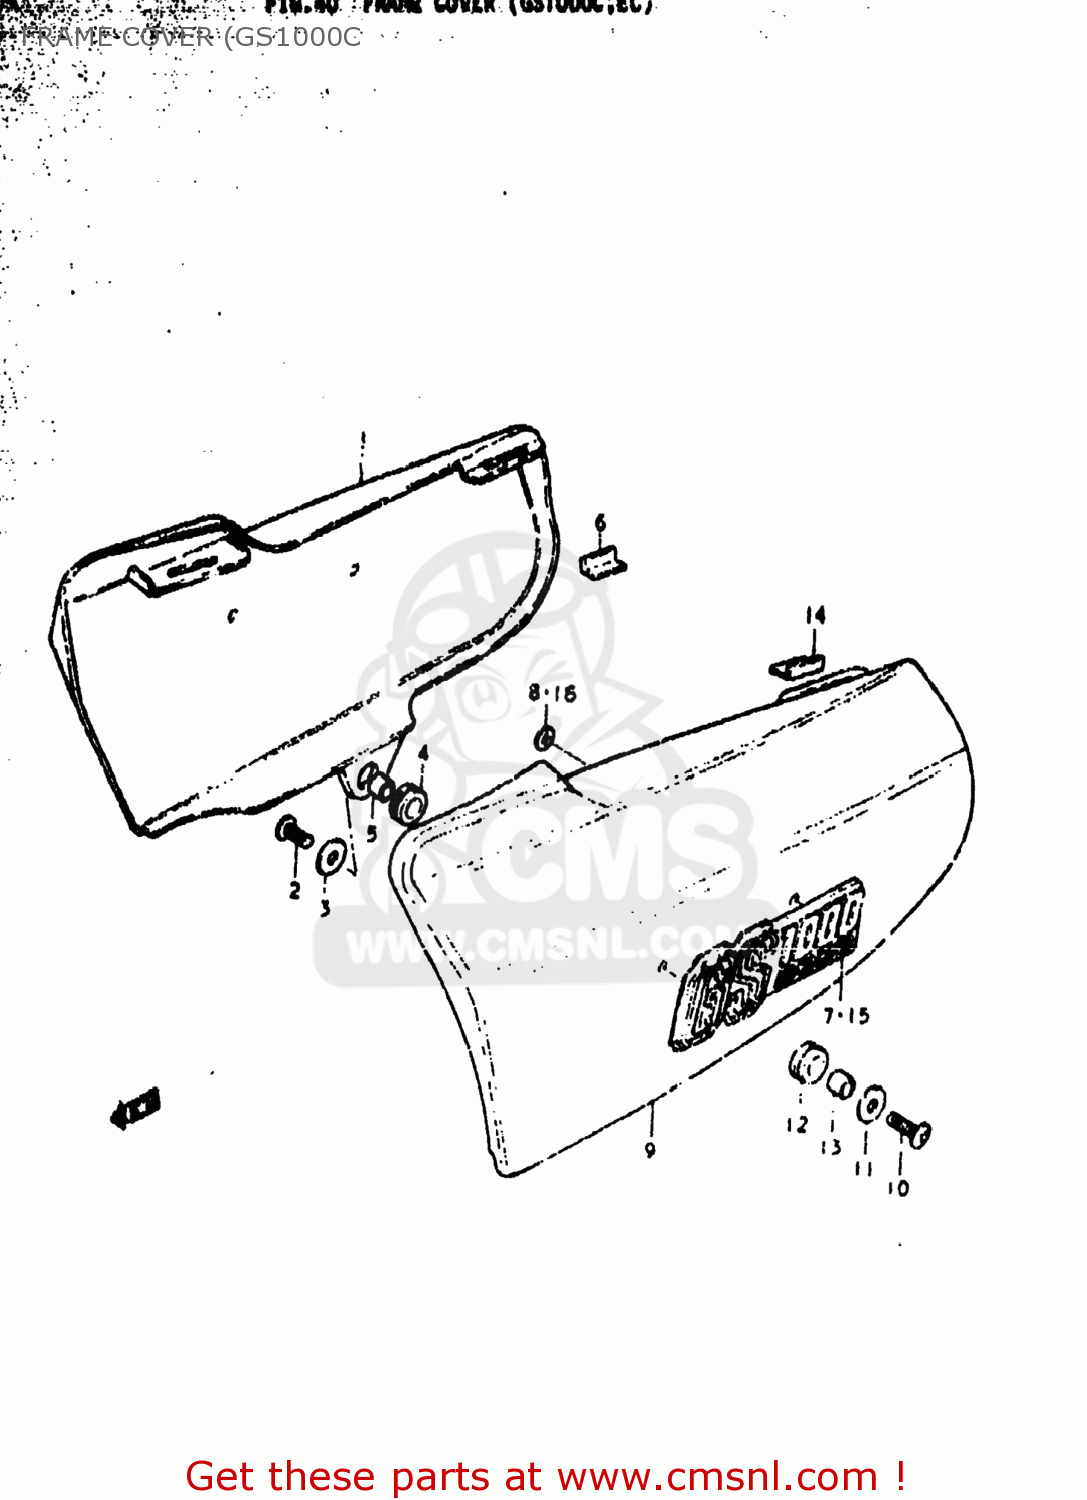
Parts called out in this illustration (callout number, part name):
1	COVER,FRAME,RIGHT
2	SCREW (6X20)
3	WASHER (6.5X18X1.6)
4	CUSHION
5	SPACER (6.8X10X10)
6	CUSHION,FRAME COVER
7	EMBLEM,FRAME COVER
8	NUT
9	COVER,FRAME,LEFT
10	SCREW (6X20)
11	WASHER (6.5X18X1.6)
12	CUSHION
13	SPACER (6.8X10X10)
14	CUSHION,FRAME COVER
15	EMBLEM,FRAME COVER
16	NUT
